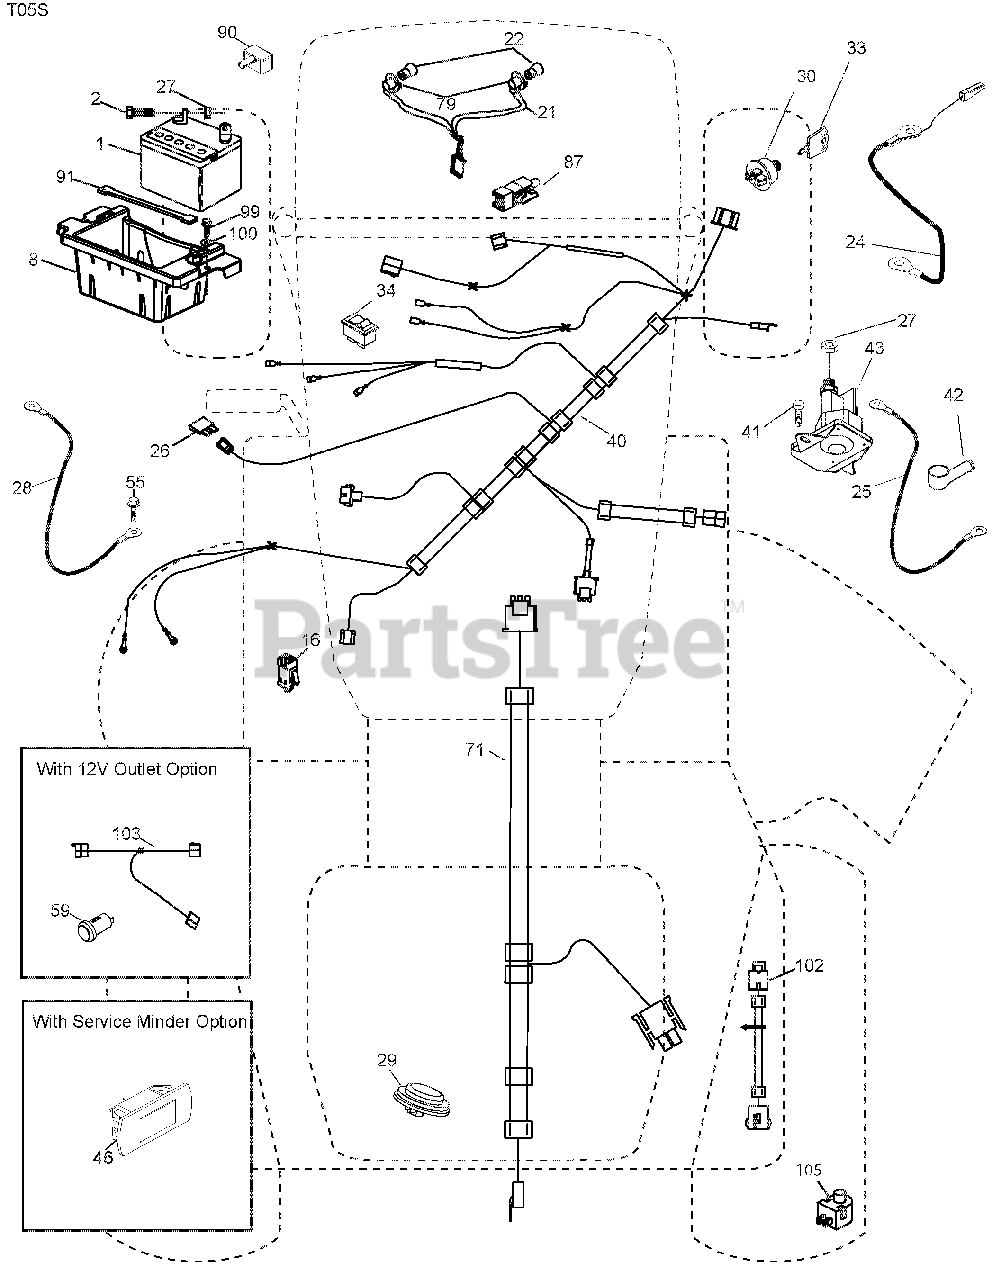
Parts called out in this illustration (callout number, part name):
1	BATTERY.12.VOLT.28.AMP.WET
2	BOLT.HEX.HD.1/4-20UNC X 3/4
8	BOX.BATTERY.MOUNT.FRONT.LT
16	SWITCH.INTERLOCK.NONO.GRAY
21	HARNESS ASM.LIGHT.22"(4152J)
22	BULB.LIGHT.#1156
24	CABLE.BTRY.PSWRE.DSH SOL.8"TEX
25	CABLE.STARTER.6GA.BL/RED.14.5"
26	FUSE.20 AMP.
27	Nut, Keps Hex 1/4-20 unc
28	CABLE.GROUND.21"BLK.6 GA.90T
29	SWITCH.SEAT.DELTA.OPC.9LB.
30	SWITCH.IGN.DLTA.P-IN.ROS
33	KEY/CHAIN.BLISTER PACK.GEN.USA
34	SWITCH.LIGHT/RESET.B/B/RED.
40	HARNESS.IGN.DASH.CBL.YTGT.PRED
41	Screw 1/4-20 x 1/2
42	COVER.TERMINAL.RED
43	SOLENOID.W/BRASS PLUNGER.2005
46	HOUR METER
55	SCREW.5/16-18X3/4.SMGML.TAP/R
71	HARNESS.IGN.CHASSIS.TEX
79	SOCKET ASM.BULB.TWISTLOCK
87	SWITCH.INTRLCK.CLUTCH.CABLE.TX
90	COVER.TERMINAL.BATTERY.FR.TEX
91	STRAP.BATTERY.MOUNT.FRONT
99	SCREW.HEXWSH.THDROL.1/4-20X3/4
100	WASHER.9/32 X 7/8 X 16GA.
102	HARNESS.PIGTAIL.K46.TEX.ROS
105	SWITCH.REVERSE.TT.PEDAL CONTRO
